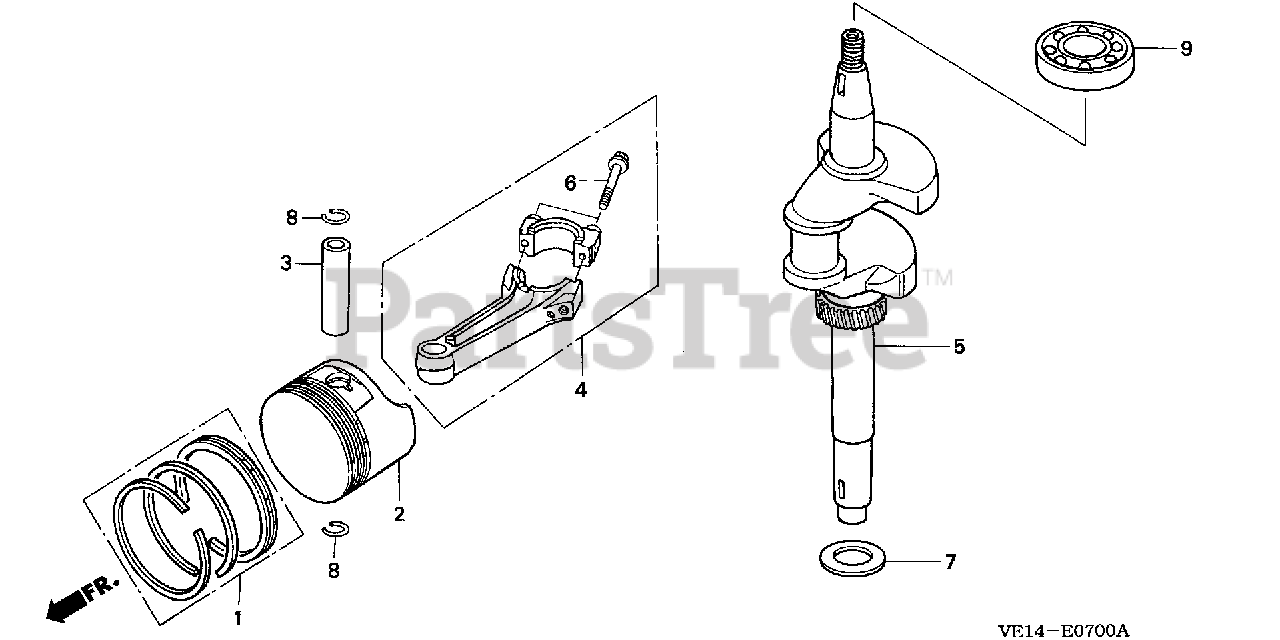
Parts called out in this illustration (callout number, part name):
1	RING SET, PISTON (STD) (GOETZE)
1	RING SET, PISTON (STD) (FEDERAL MOGUL)
1	RING SET, PISTON (STD) (NIPPON)
1	RING SET, PISTON (0.25) (FEDERAL MOGUL)
1	RING SET, PISTON (0.25) (NIPPON)
1	RING SET, PISTON (0.50) (FEDERAL MOGUL)
1	RING SET, PISTON (0.50) (TEIKOKU)
1	RING SET, PISTON (0.75) (GOETZE)
1	RING SET, PISTON (0.75) (FEDERAL MOGUL)
1	RING SET, PISTON (0.75) (NIPPON)
2	PISTON (STD)
2	PISTON (0.25)
2	PISTON (0.50)
2	PISTON (0.75)
3	PIN, PISTON
4	ROD ASSY., CONNECTING
4	ROD ASSY., CONNECTING (0.25 LOWER SIZE)
5	CRANKSHAFT
6	BOLT, CONNECTING ROD
7	WASHER C, THRUST (25MM)
8	CLIP, PISTON PIN (13MM)
9	BEARING, RADIAL BALL
